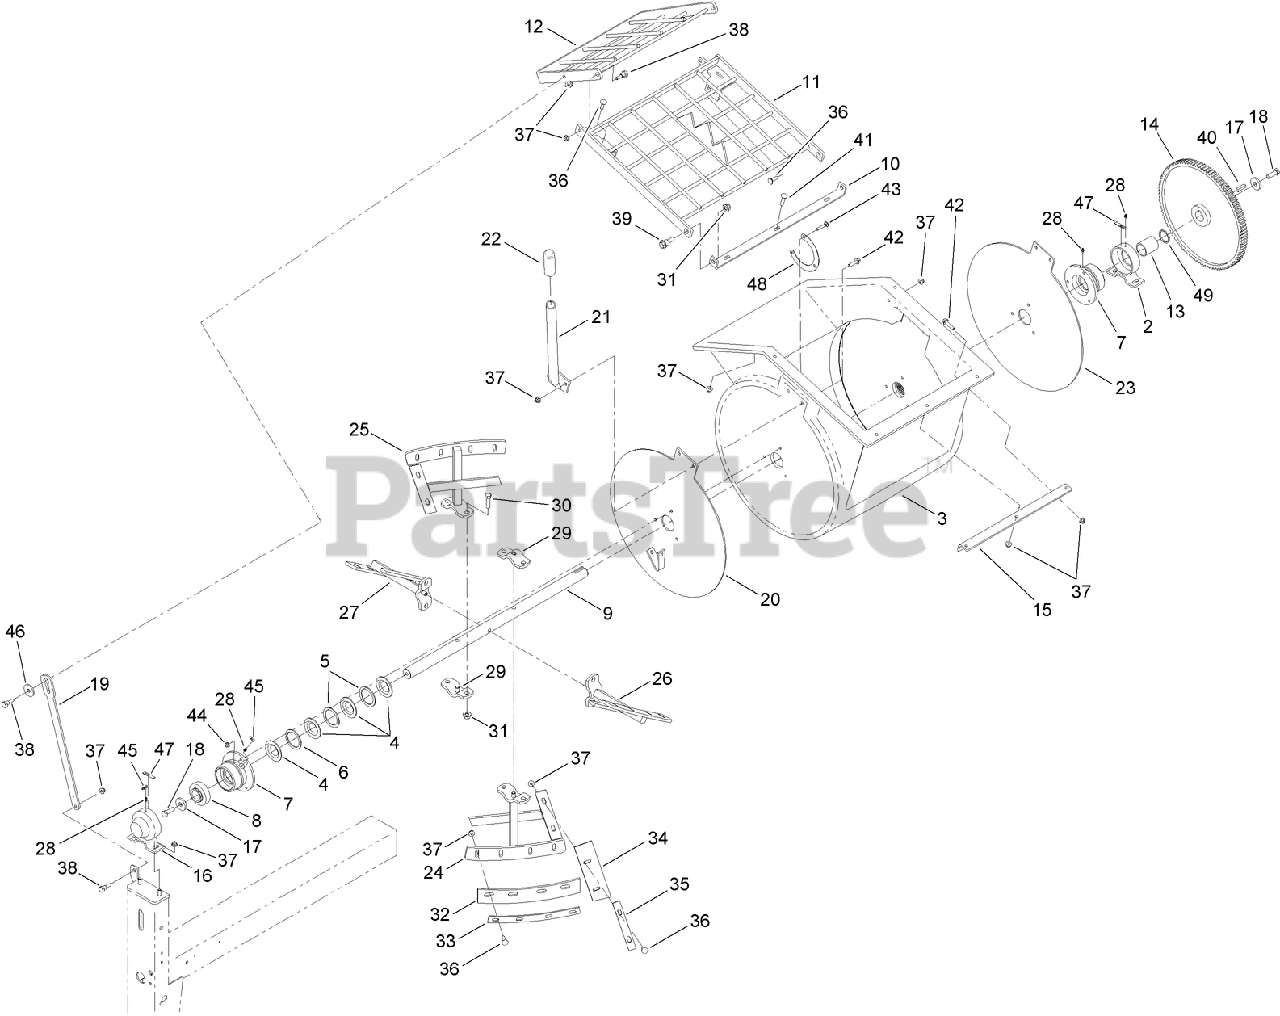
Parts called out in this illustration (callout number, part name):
2	TRUNNION
4	SEAL-DRUM
5	WASHER-FLAT
6	WASHER-SPLIT
7	HOUSING-BEARING
8	BEARING-BALL
9	SHAFT-DRUM
10	MOUNT-GUARD
11	GUARD-STATIONARY
12	GUARD-DRUM
13	SPACER-SHAFT, DRUM
14	GEAR-94 TEETH
15	SUPPORT-GUARD
16	TRUNNION-CAPPED
17	WASHER-FLAT
18	SCREW-HH
19	BAR-GUARD, LIFTER
20	END-DRUM
22	GRIP-HAND
23	END-DRUM
28	FITTING-GREASE
30	SCREW-HH
31	NUT-LOCK
32	BLADE-RUBBER, LONG
33	BAR-BACKER, LONG
34	BLADE-RUBBER, SHORT
35	BAR-BACKER, SIDE
36	BOLT-CARR
37	NUT-HF, NI
38	BOLT-SHOULDER
39	SCREW-SHOULDER, HHF
40	KEY-SQUARE
41	SCREW-CARR
42	SCREW-HHF
43	SCREW-CARR
44	NUT-HF, NI
45	CAP-PLUG
46	Washer-Thrust
47	DECAL-GREASE
48	SPACER-BOLT
49	SPACER-SHAFT, DRUM
